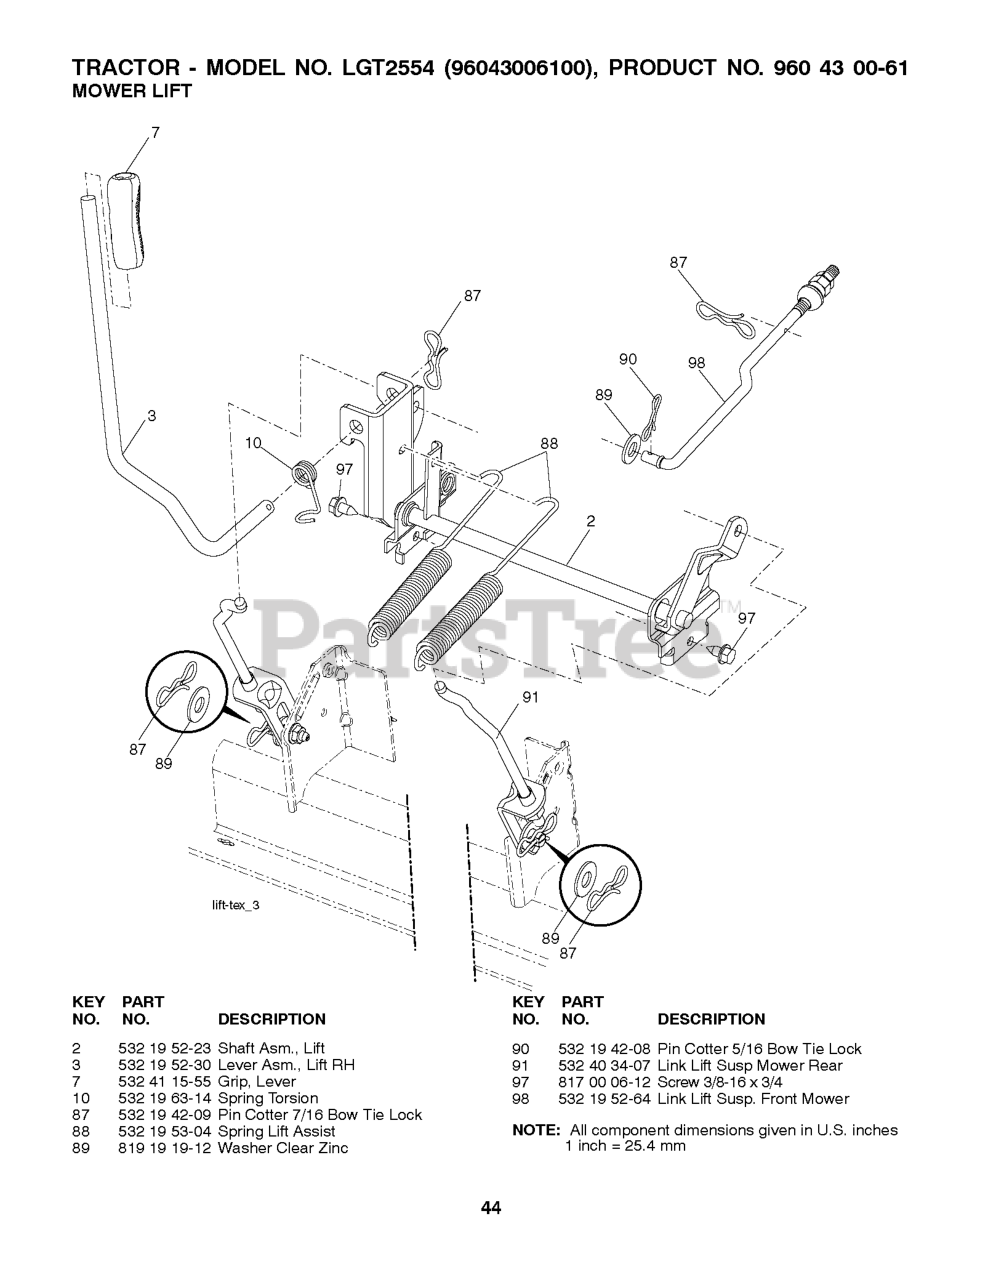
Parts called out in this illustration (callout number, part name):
2	SHAFT.ASM.LIFT.CROSS.H
3	LEVER.LIFT.HANDLE.GT
7	GRIP.HANDLE.LIFT.PVC.BLACK
10	SPRING.TORSION.LIFT.HANDLE
87	PIN.COTTER.7/16.BOW TI.
88	SPRING.LIFT.ASSIST.GT2
89	WASHER.CLEAR.ZINC
90	PIN.COTTER.5/16.BOW TI
91	LINK.ASM.LIFT.54"TG
97	SCREW, 3/8-16X3/4
98	LINK.ASM.SUSP.FRONT.MWR.10.5
